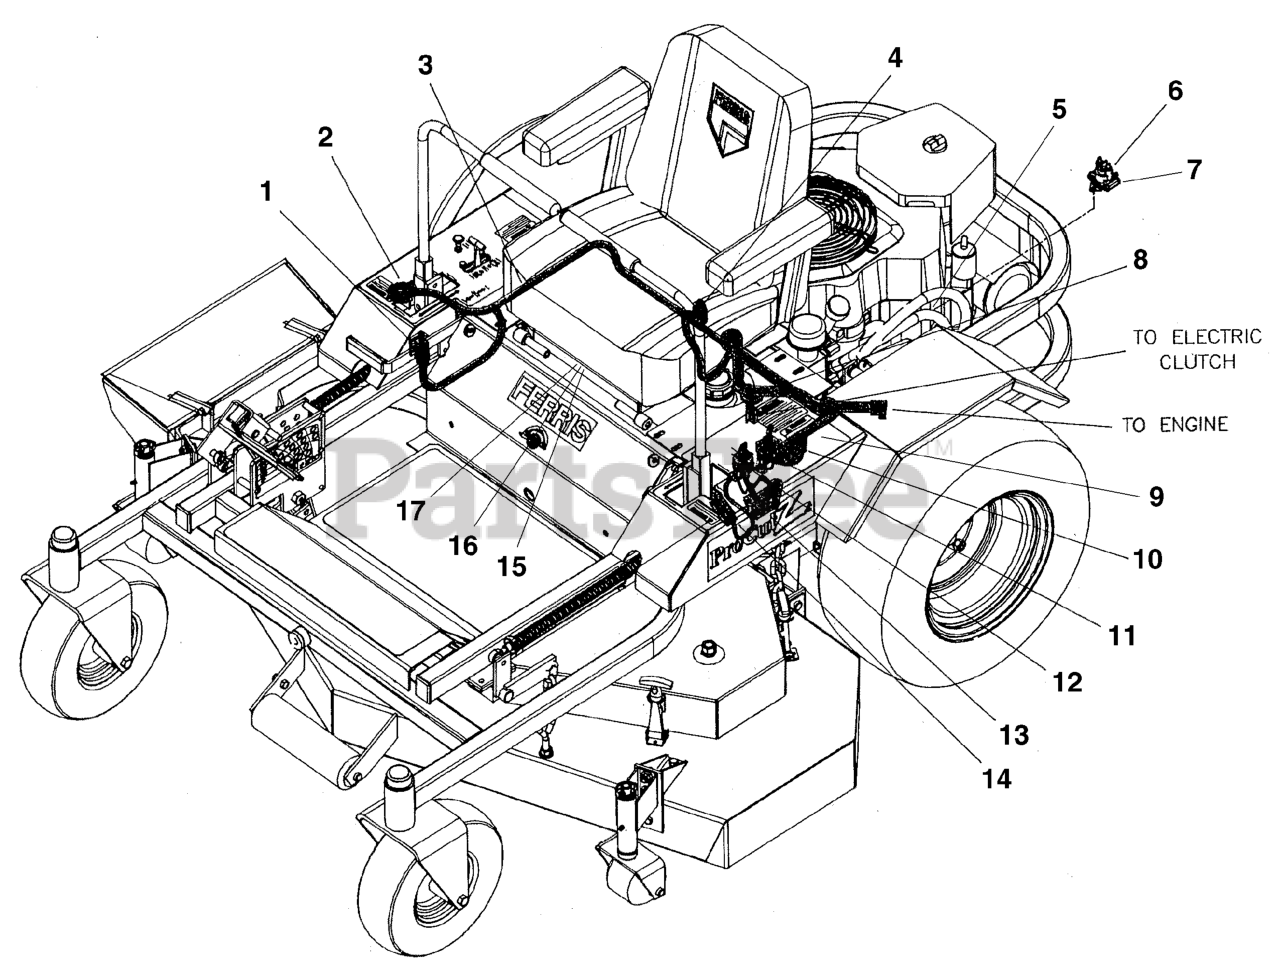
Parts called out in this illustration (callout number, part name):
1	SWITCH, Plunger, NO/NC
2	SWITCH, PLUNGER, N.O./N.C.
3	HARNESS, Wire PCZ
4	SWITCH, Plunger, NO
5	CABLE, Starter
6	SOLENOID, Starter
7	STARTER JUMPER WIRE
8	GROMMET, 7/8"
9	HOUR METER
10	SWITCH, Safety Interlock
11	SWITCH, Electric Clutch
12	SWITCH, IGNITION, 6 POST
13	FUSE BLOCK
14	SWITCH, PLUNGER, N.O./N.C.
15	CABLE, Positive (+) Battery
16	BATTERY CABLE, NEG, 22, 1/4-5/16
17	CABLE, Ground
